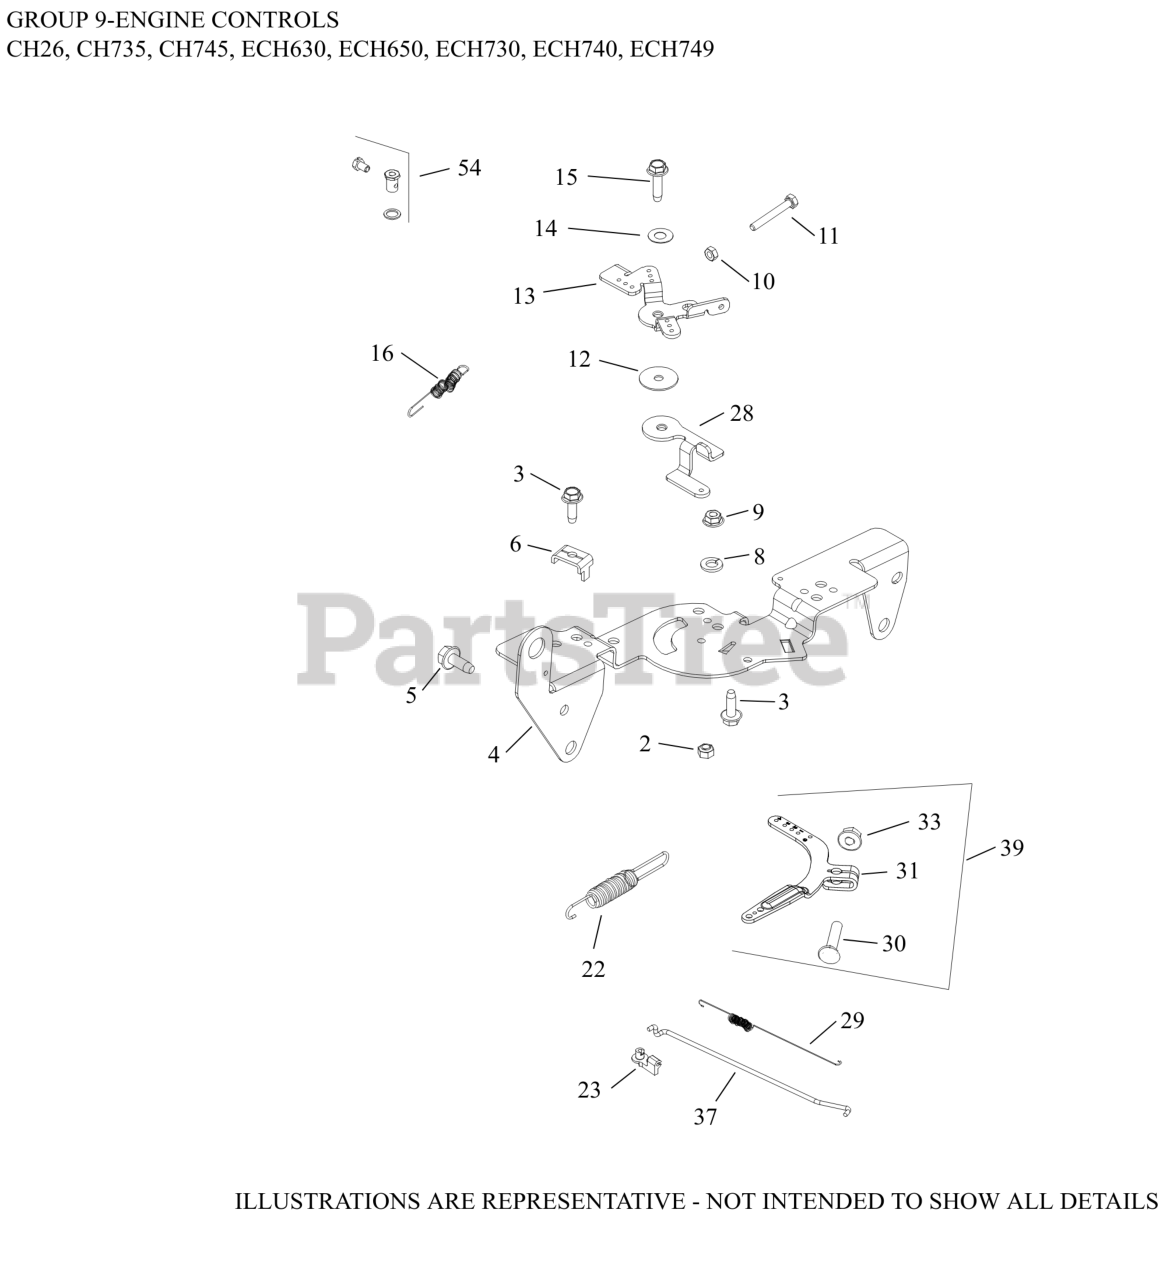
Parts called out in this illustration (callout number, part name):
2	NUT, LOCK M5X.8
3	SCREW, THREAD FORMING
4	BRACKET, CONTROL-(#24126263S)
5	SCREW, THREAD FORMING
6	CLAMP, CABLE-(#2523753S)
8	WASHER, SPRING LOCK 1/4"
9	NUT, FLG M5X.8
10	NUT, M4X0.7
11	SCREW, CAP M4X.7X30
12	WASHER, FLAT 5.5 MM
13	LEVER, THROTTLE CONTROL
14	WASHER, SPRING 1/4"
15	SCREW, THD FRM-USE 25 086 473-S
16	SPRING, THROTTLE LIMITER
22	SPRING, GOVERNOR (BLACK)
23	BUSHING, THROTTLE LINKAGE
28	LEVER, THROTTLE ACTUATOR
29	SPRING, LINKAGE
30	BOLT, RD HD SQ NECK M6X1.0X25
31	LEVER, GOVERNOR - (#2409069S)
33	NUT, FLG M6X1.0
37	LINKAGE, THROTTLE
39	LEVER, GOVERNOR ASSEMBLY
54	KIT, CLAMP
NI	SCREW, IND SLT HD 8-32X1/4"
